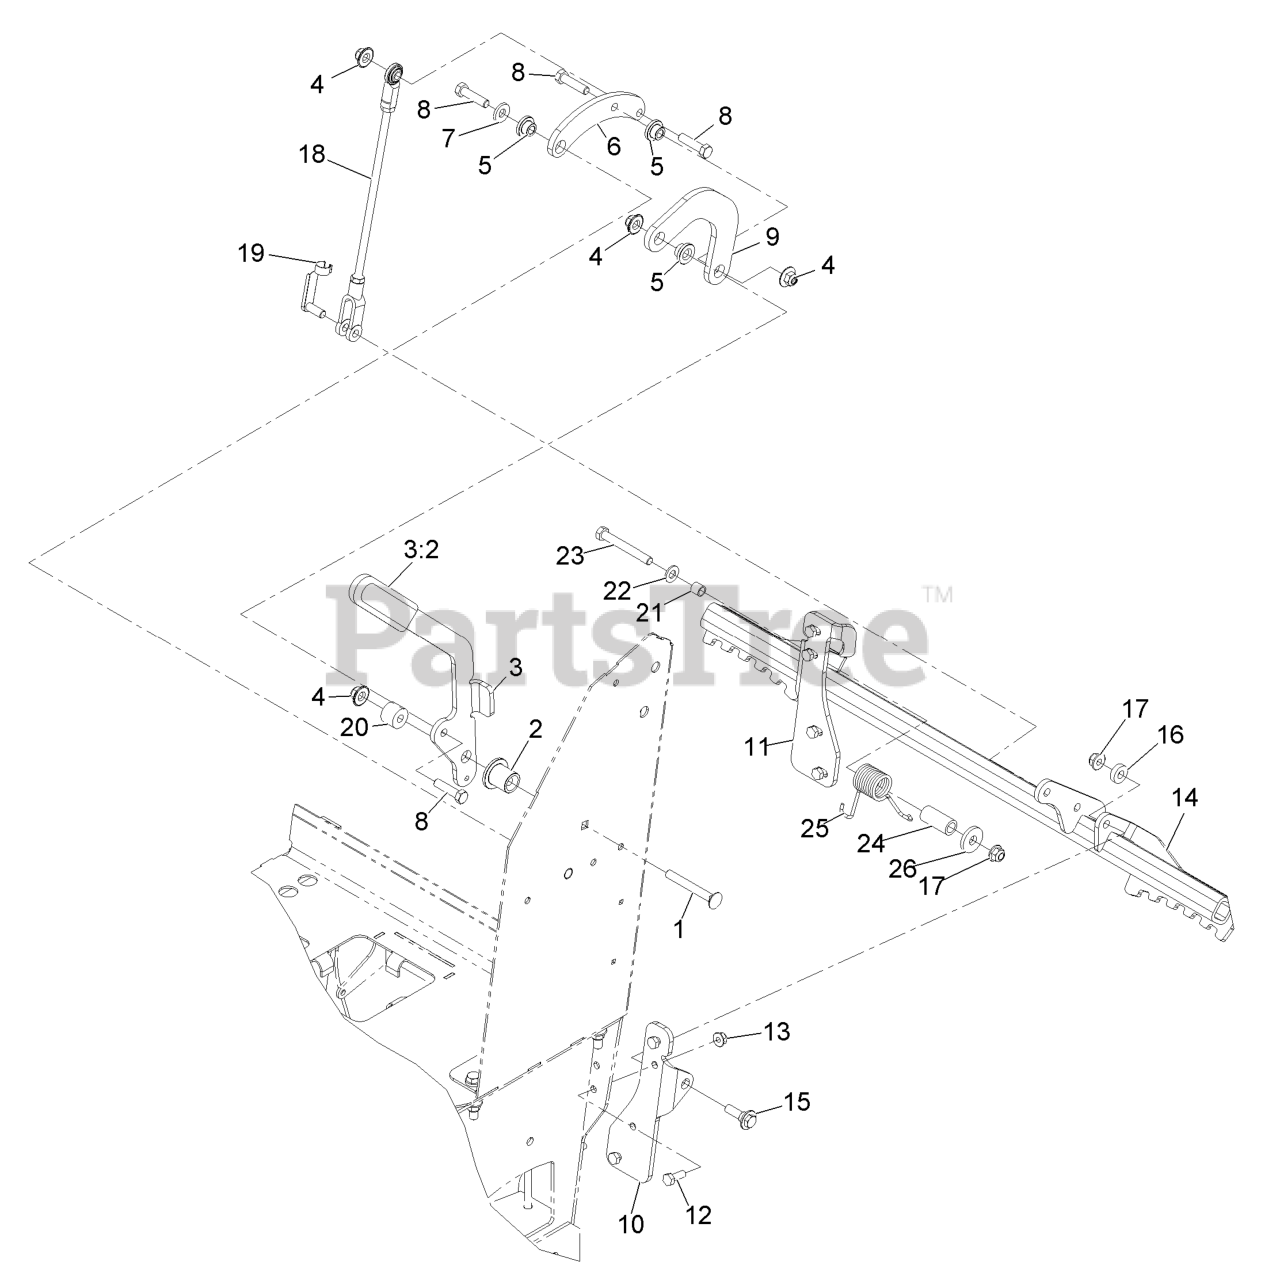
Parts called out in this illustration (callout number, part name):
1	SCREW-CARR
2	BUSHING-HANDLE
3	HANDLE-W/GRIP ASM
3:2	GRIP-LEVER
4	Nut-Nyloc 3/8-16 Flg
5	BUSHING-FLANGED
6	ARM-BRAKE BELLCRANK
7	WASHER-BELLEVILLE
8	SCREW-HH
9	LINK-BRAKE HANDLE
10	BRACKET-BRAKE MOUNT, LH
11	BRACKET-BRAKE MOUNT, RH
12	SCREW-HH
13	NUT-HF, NI
14	BAR-BRAKE
15	SCREW-SHOULDER, HWH
16	SPACER
17	NUT-HF, NI
18	ASM-BRAKE LINKAGE
19	PIN-SPRING, CLEVIS
22	WASHER-FLAT
23	SCREW-CARR
25	SPRING-TORSION
